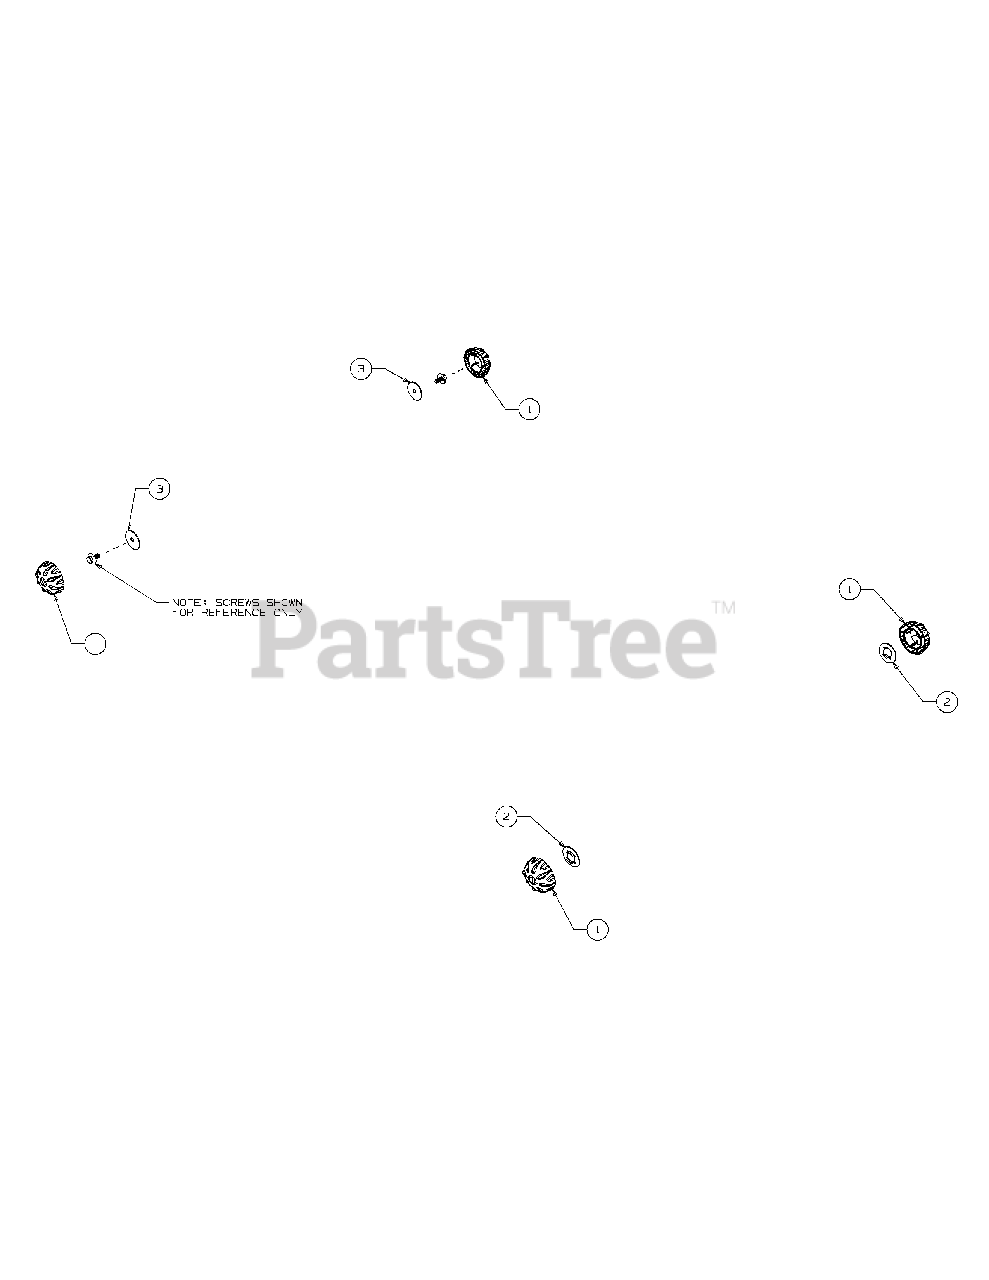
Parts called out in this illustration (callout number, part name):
1	Hub Cap
2	Washer-Flat .781 I
3	Wash:Flt:.350X1.59
